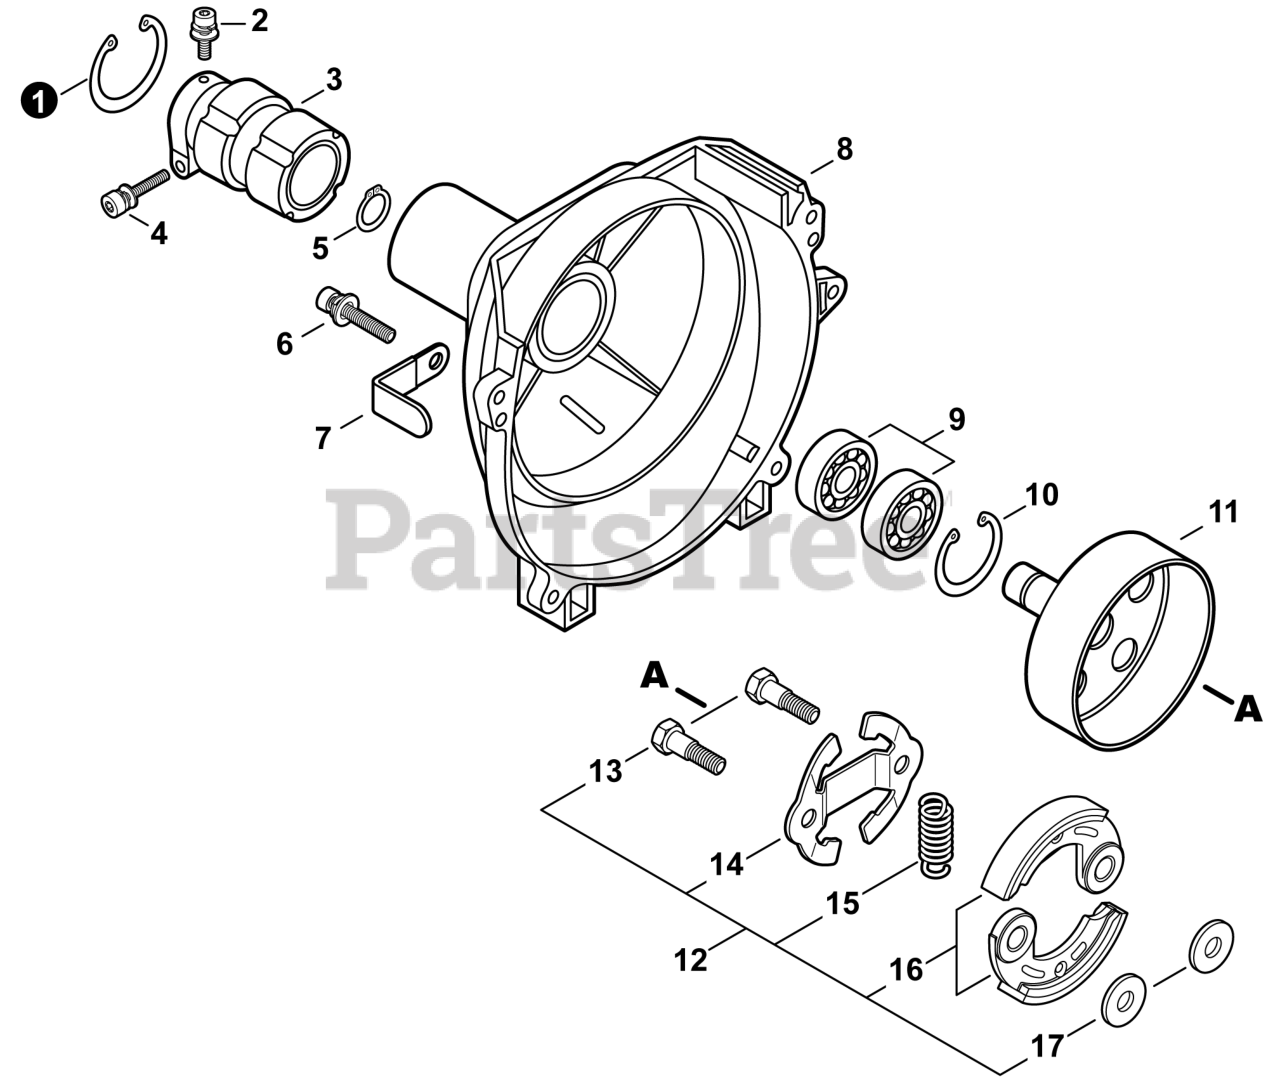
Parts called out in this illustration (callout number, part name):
1	RING, RETAINING 45
2	BOLT 5x12
3	CUSHION
4	BOLT 5x28
5	RING, SNAP 12
6	BOLT 5x20
8	COVER, FAN
9	BEARING, BALL 6001
10	RING, SNAP 28
11	DRUM, CLUTCH
12	CLUTCH ASSY
14	SPRING, FLAT
15	SPRING, TENSION
16	SHOE, CLUTCH
17	WASHER 8.2x17x1.6
